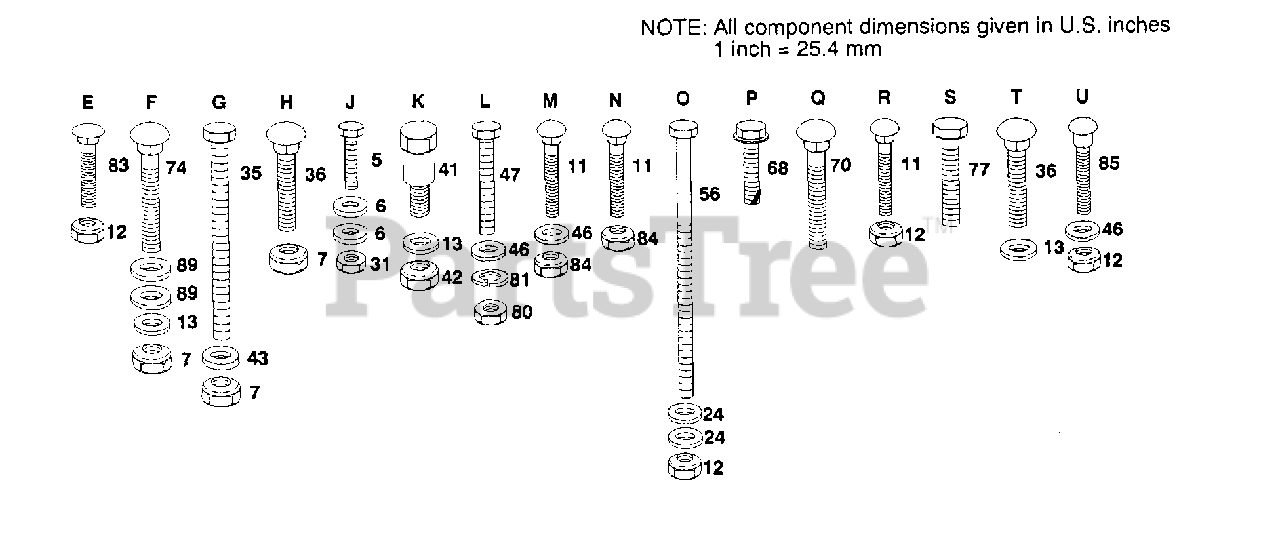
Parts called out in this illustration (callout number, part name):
5	BOLT LT
6	WASHER
11	BOLT
13	WASHER
24	WASHER M
35	BOLT - HEX 3/8 - 16 X 3
41	BOLT SHOULDER
42	NUT, CENTERLOCK
43	WASHER
46	WASHER
56	BOLT
68	SCREW
70	BOLT
74	BOLT
77	BOLT
80	NUT.HEX.5/16-18
81	LOCKWASHER
83	BOLT
89	WASHER
